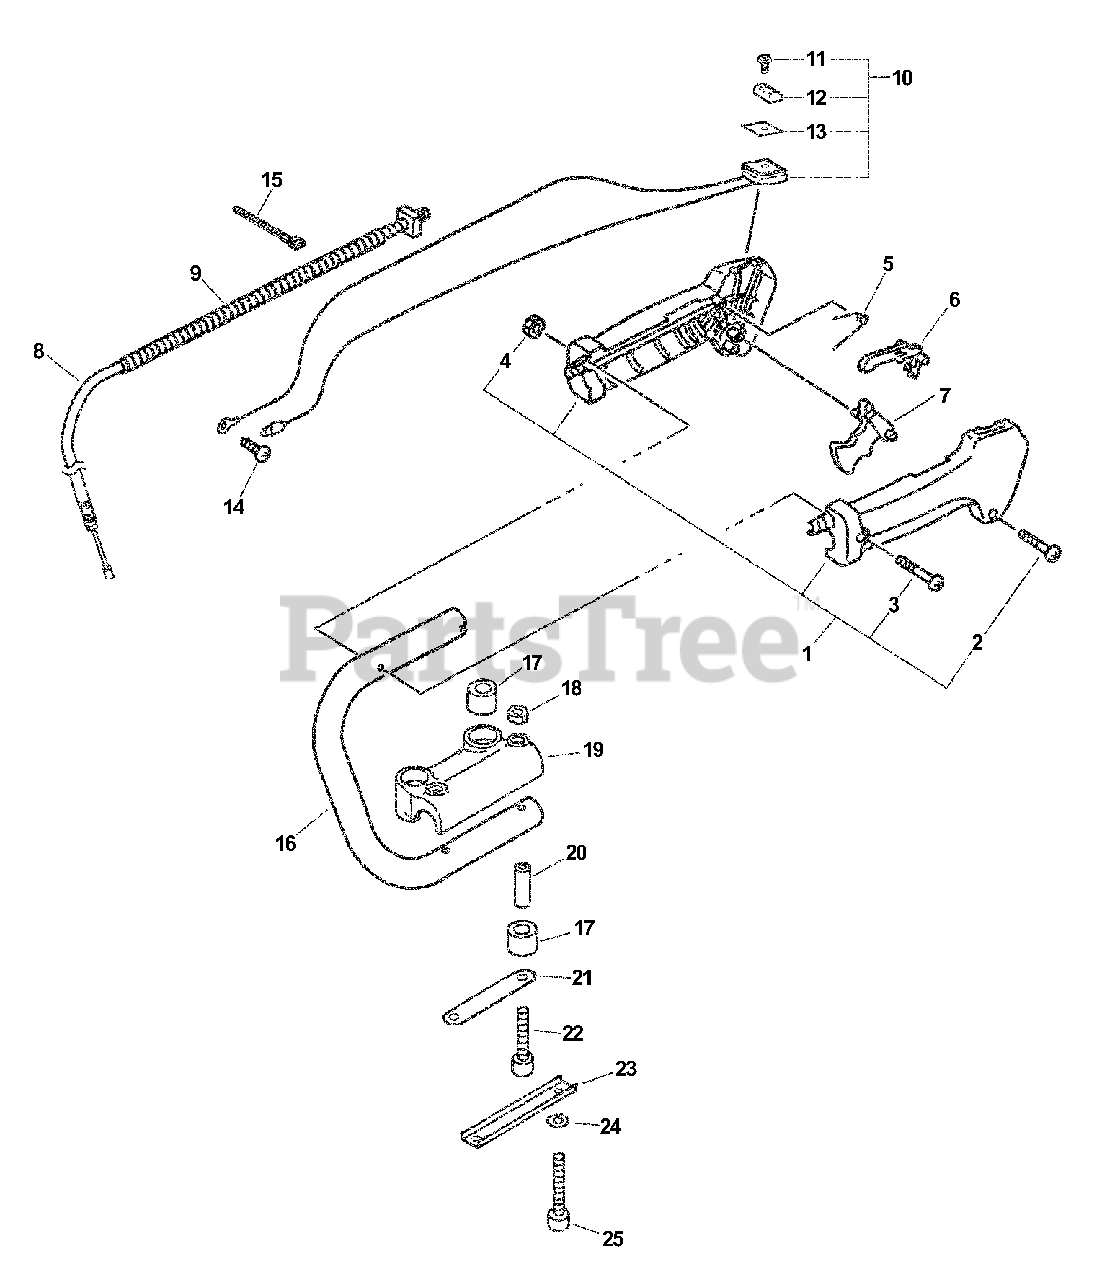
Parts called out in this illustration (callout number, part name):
1	THROTTLE CONTROL ASSY
2	SCREW - 3X25
3	SCREW - 5X30
5	SPRING, LOCKOUT LEVER
6	LOCKOUT, THROTTLE
7	TRIGGER, THROTTLE
8	CABLE, THROTTLE
10	IGNITION SWITCH ASSY
11	SCREW - 3X10
12	KNOB, SWITCH - ORANGE
13	COVER, SWITCH - STOP
14	SCREW - 5X10
15	TIE, CABLE
16	HANDLE - REAR
19	BRACKET, HANDLE - UPPER
20	SPACER
22	SCREW - 5X40
23	BRACKET, HANDLE - LOWER
25	SCREW - 5X35
